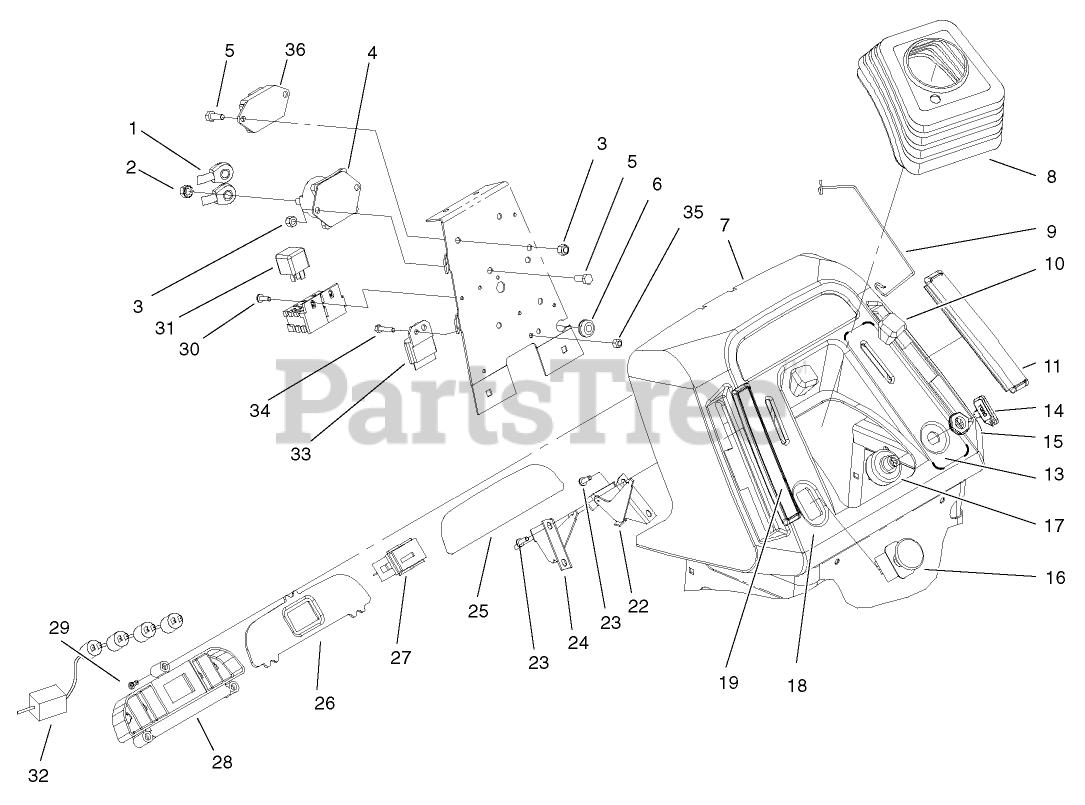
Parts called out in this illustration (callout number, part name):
1	CABLE-BATTERY, RED
2	NUT-KEPS
3	NUT-LOCK, NI
4	SOLENOID
5	SCREW-HH
6	GROMMET-RUBBER
8	BOOT-STEERING
9	CLIP-BOOT
11	COVER-SLOT, RH
13	DECAL-DASH
13	DECAL-THROTTLE, IGNITION
14	KEY-IGNITION
16	SWITCH-PTO,ON-ON-NONE
17	SWITCH-IGNITION
18	DECAL-DASH, PTO/CHOKE
18	DECAL-PTO / CHOKE
19	COVER-SLOT, LH
22	CONTROL-THROTTLE
24	CONTROL-CHOKE
26	LENS-DASH
27	HOURMETER
28	HOUSING-LIGHT, INDICATOR
29	SCREW
30	SCREW-PPHTF
31	RELAY
32	HARNESS-4 LAMP
33	MODULE-LOW VOLTAGE
35	NUT-LOCK, NI
36	MODULE-CLUTCH
